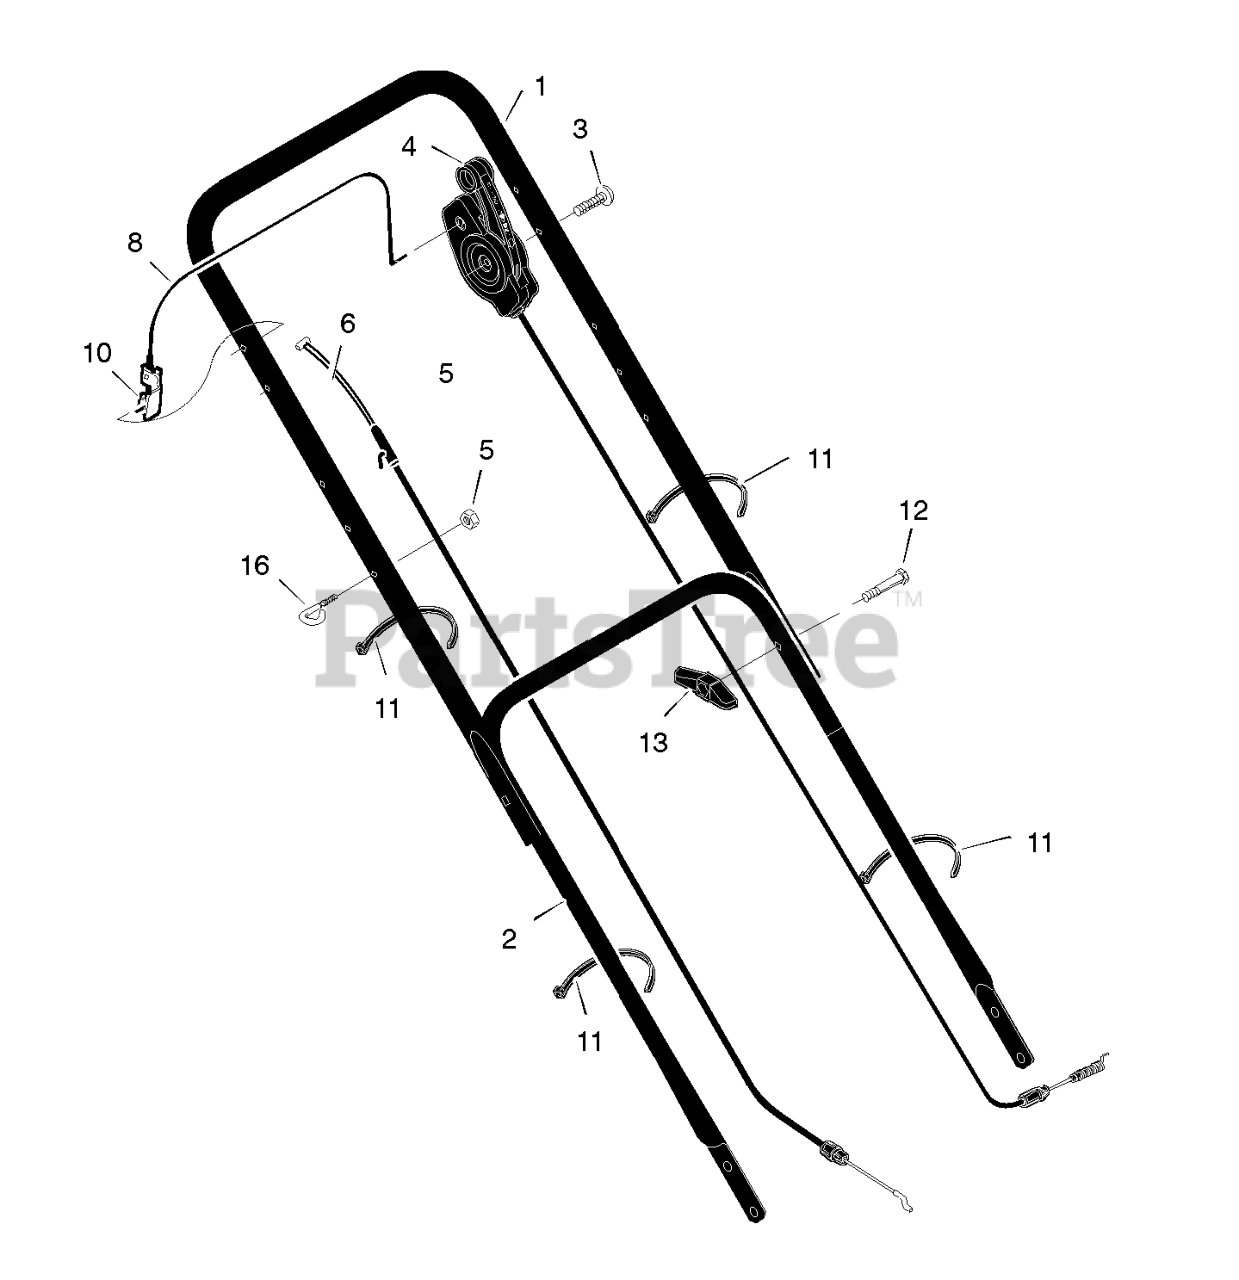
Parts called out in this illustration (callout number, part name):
1	Handle, Upper (Black)
2	Handle, Lower (Black)
4	Control, Drive
5	Locknut
6	Cable, Stop
8	Lever, Stop
10	Bracket, Stop Lever
11	Fastener, Cable
13	Knob
16	Guide, Rope
